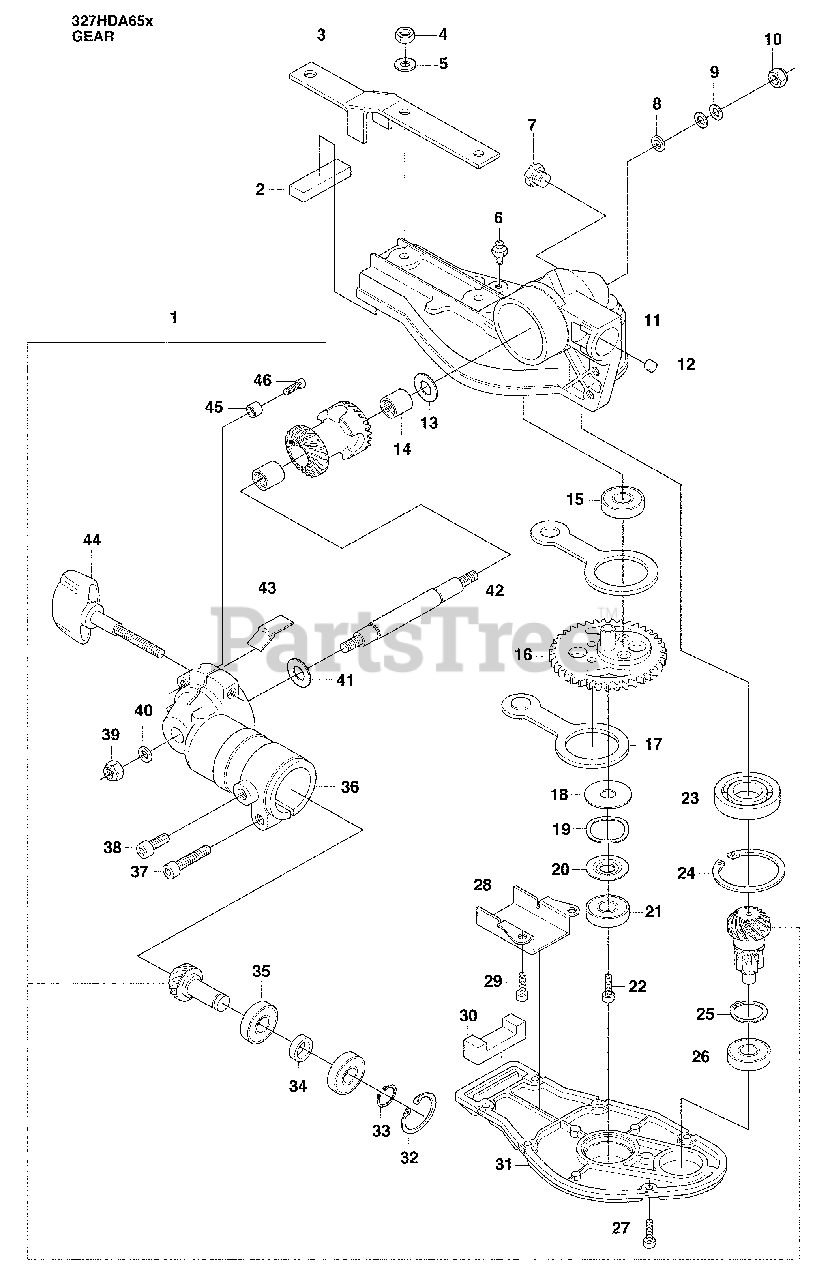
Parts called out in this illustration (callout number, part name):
2	Gasket
5	Washer, 7/32 X 1/2 X 16 Gauge
6	GREASE NIPPLE
8	Washer, M6
10	Hex Flange Nut, M6
11	Gear Housing
14	Support Bushing
15	Ball Bearing
17	Connecting Rod
21	Ball Bearing
22	Screw, MC6S 5 X 10
23	Ball Bearing
24	Retaining Ring
25	Retaining Ring
26	Ball Bearing
27	Socket Head Capscrew, M4 X 0.7 X 12
29	Screw, MC6S 4 X 8
30	Gasket
32	Retaining Ring
33	Retaining Ring
35	Ball Bearing
36	Gear Housing
37	Screw, M5 X 25 Pl Hsc Ih X
38	Screw, M5 X 12 Ms Hcs Ih X
39	Hex Flange Nut, M6
40	Washer, M6
46	Screw, MC6S 5 X 16
